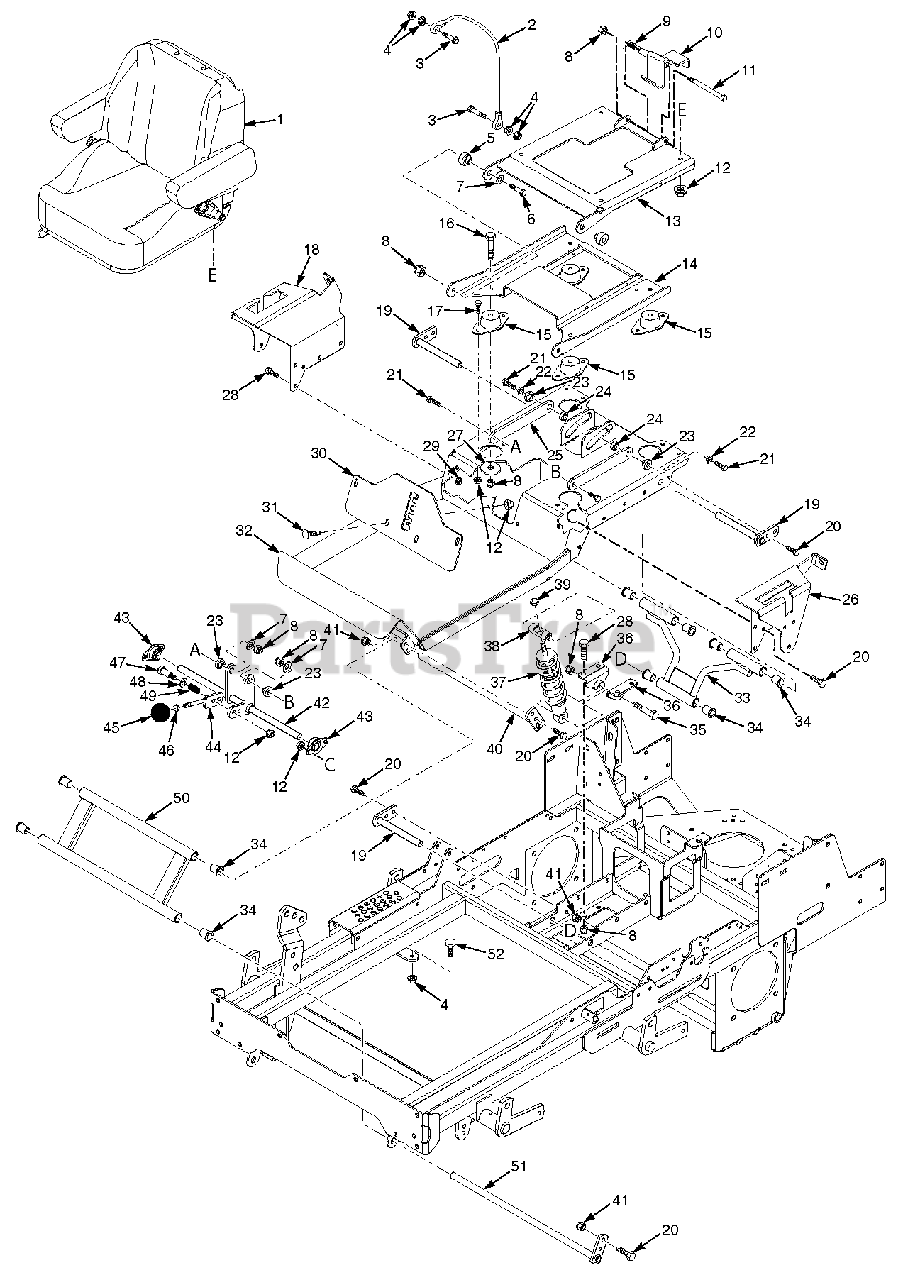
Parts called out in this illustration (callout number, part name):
1	Seat Assembly
2	Cable, Seat Stop
3	Bolt, Hex Head 1/4-20 x 1-1/4"
4	Nut, Serrated Flange 1/4-20
5	Sleeve, Seat Base Mount
6	Bolt, Hex Head 3/8-16 x 2"
7	Flatwasher, 3/8-.391 x .938 x .105
8	Nut, Elastic Stop 3/8-16
9	Spring, Seat Latch
10	Latch Weldment, Seat
11	Bolt, Hex Head 3/8-16 x 6"
12	Nut, Serrated Flange 5/16-18
13	Seat Plate Weldment
14	Seat Mounting Plate Weldment w/Decal
15	Isolator, Seat
16	Bolt, Hex Head 3/8-16 x 2-1/4"
17	Bolt, Hex Head 5/16-18 x 3/4"
18	Bracket Weld., Control Lever RH w/Decal
19	Shaft Weldment, Rear Op. Platform Pivot
20	Bolt, Hex Head 5/16-18 x 1"
21	Bolt, Hex Head 3/8-16 x 1-1/2"
22	Lockwasher, 3/8" Spring
23	Bushing
24	Bearing
25	Link, Suspension Seat Tensioner
26	Bracket Weld., Control Lever LH w/Decal
27	Flatwasher, 3/8-.406 x 2.25 x .188
28	Bolt, Hex Head 3/8-16 x 1"
29	Nut, Serrated Flange 3/816
30	Bracket, Suspension Adjustment w/Decal
31	Bolt, Carriage 5/16-18 x 1"
32	Seat Mounting Base Weldment w/Decal
33	Suspension Pivot Assembly, Rear
34	Bearing
35	Bolt, Hex Head 3/8-16 x 2-3/4"
36	Mount Weldment, Shock
37	Shock Absorber, Suspension
38	Mount, Suspension Shock
39	Nut, Elastic Stop 3/8-24 Grade 8
40	Pin Weldment, Op Platform Upper Pivot
41	Nut, Elastic Stop 5/16-18
42	Pivot Weldment, Suspension Tensioner
43	Bearing, Self Align 5/8" ID
44	Adjustment Lever, Suspension
46	Nut, Jam 3/8-16
47	Bolt, Shoulder 3/8 x 1"
48	Flatwasher, 3/8-.406 x .812 x .065
49	Spring
50	Suspension Pivot Assembly, Front
51	Pin Weldment, Op Platform Lower Pivot
52	Bumper, Rubber
